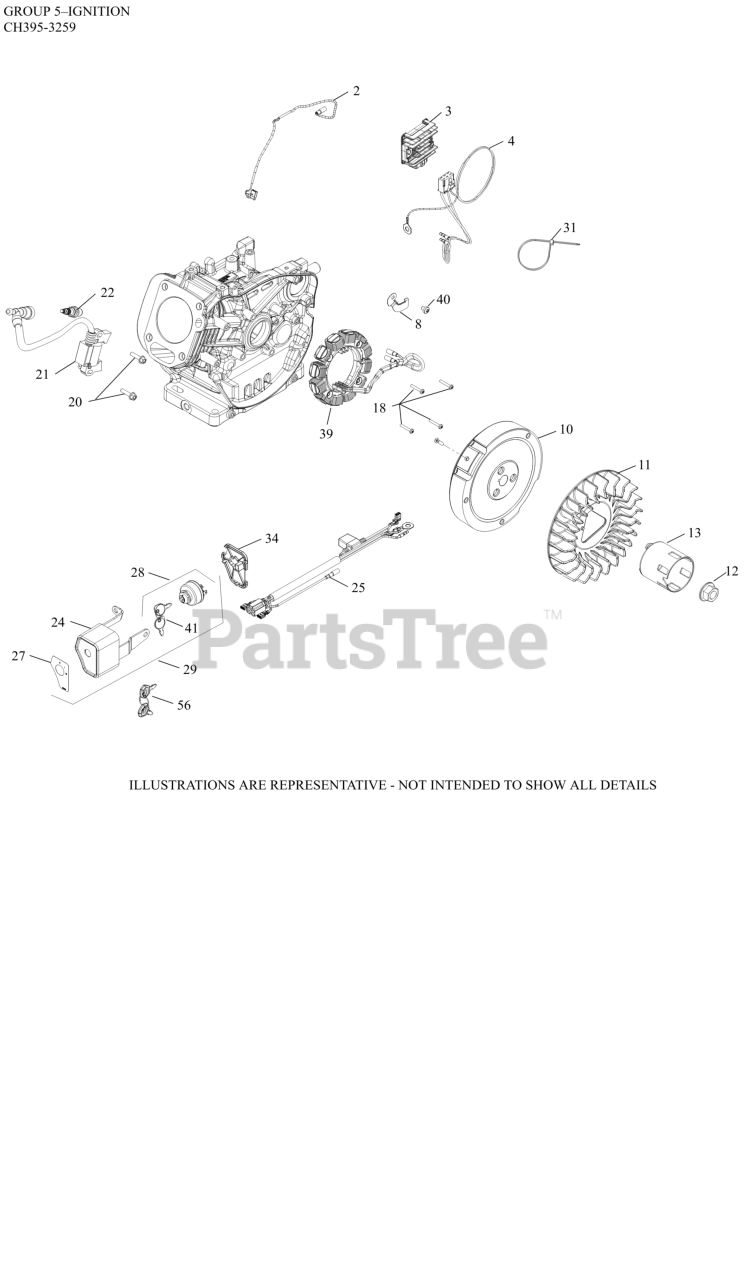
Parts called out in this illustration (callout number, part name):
2	LEAD, GROUND TO KILL
3	REGULATOR, 18 AMP
4	HARNESS, REGULATOR WIRING ASSY
8	BRACKET, STATOR WIRE
10	FLYWHEEL ASSY ELECTRIC START (CH395)
11	FAN, FLYWHEEL
12	NUT, FLYWHEEL
13	CUP, STARTER DRIVE
18	SCREW, STATOR MOUNTING
20	SCREW, M6 X 25-(#25086436S)
21	MODULE, SPARK PLUG ASSY
22	SPARK PLUG
24	KIT, KEYBOX HOUSING ASSEMBLY
25	HARNESS, WIRING ASSEMBLY (18 AMP)
27	LABEL, KEY BOX
28	SWITCH, KEY ASSEMBLY
29	KIT, KEY BOX ASSEMBLY
34	COVER, KEY BOX
39	STATOR ASSEMBLY, 18A
40	SCREW, COIL BRACKET
56	KIT, KEY PLASTIC HANDLE (2 PC)
